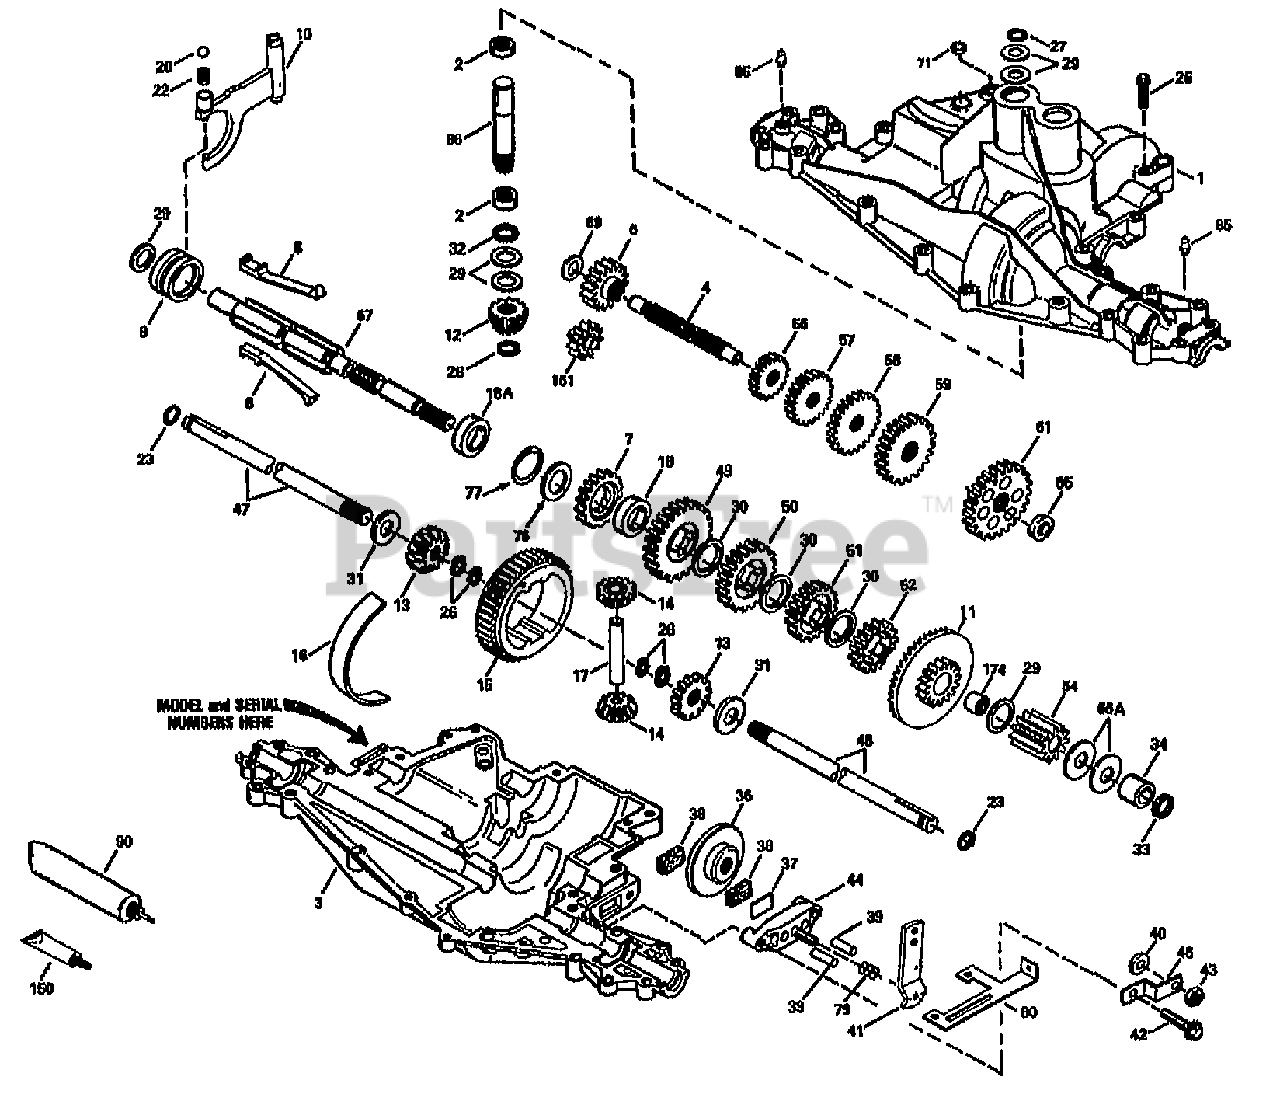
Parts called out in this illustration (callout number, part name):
1	TRANSAXLE COVER
2	NEEDLE BEARING
3	TRANSAXLE CASE
4	COUNTERSHAFT
6	SPUR GEAR (16 TEETH)
7	SPUR GEAR (22 TEETH)
8	SHIFT KEY
9	SHIFT COLLAR
10	SHIFT ROD & FORK
11	BEVEL GEAR & BEARING (INCL. 174)
12	BEVEL PINION (14 TEETH)
13	BEVEL GEAR (16 TEETH)
14	DIFFERENTIAL PINION
15	RING GEAR
16	BEARING STRIP
17	DRIVE PIN
18	NEUTRAL SPACER
18A	NEUTRAL SPACER
20	BALL, 5/16" DIA.
22	SPRING
23	SEAL RING
25	SCREW, 1/4-20 X 1-1/4"
26	RETAINING RING
27	RETAINING RING
28	RETAINING RING
29	WASHER
30	WASHER
32	"O" RING
33	"O" RING
36	BRAKE DISK
37	BRAKE PAD PLATE
38	BRAKE PAD (PKG OF 2)
39	DOWEL PIN
41	BRAKE LEVER
42	SCREW, 1/4-20 X 1-1/4"
43	LOCKNUT, 5/16-24
44	BRAKE PAD HOLDER
46	BRAKE LEVER BRACKET
47	AXLE (16-1/4" LONG)
48	AXLE (11" LONG)
49	SPUR GEAR (30 TEETH)
50	SPUR GEAR (25 TEETH)
51	SPUR GEAR (22 TEETH)
52	SPUR GEAR (19 TEETH)
54	SPUR GEAR (11 TEETH)
56	SPUR GEAR (20 TEETH)
57	SPUR GEAR (25 TEETH)
58	SPUR GEAR (28 TEETH)
59	SPUR GEAR (30 TEETH)
61	SPUR GEAR (34 TEETH)
66	INPUT SHAFT
67	SHIFTER & BRAKE SHAFT
71	SQUARE CUT RING
77	INVERTED RETAINING RING (PKG OF 2)
80	BRAKE BRACKET
85	LUBRICATION FITTING
90	GREASE (32OZ. BTL. BENTONITE GREASE)
150	GASKET ELIMINATOR (LOCTITE #515)
161	REVERSE IDLER
174	NEEDLE BEARING
